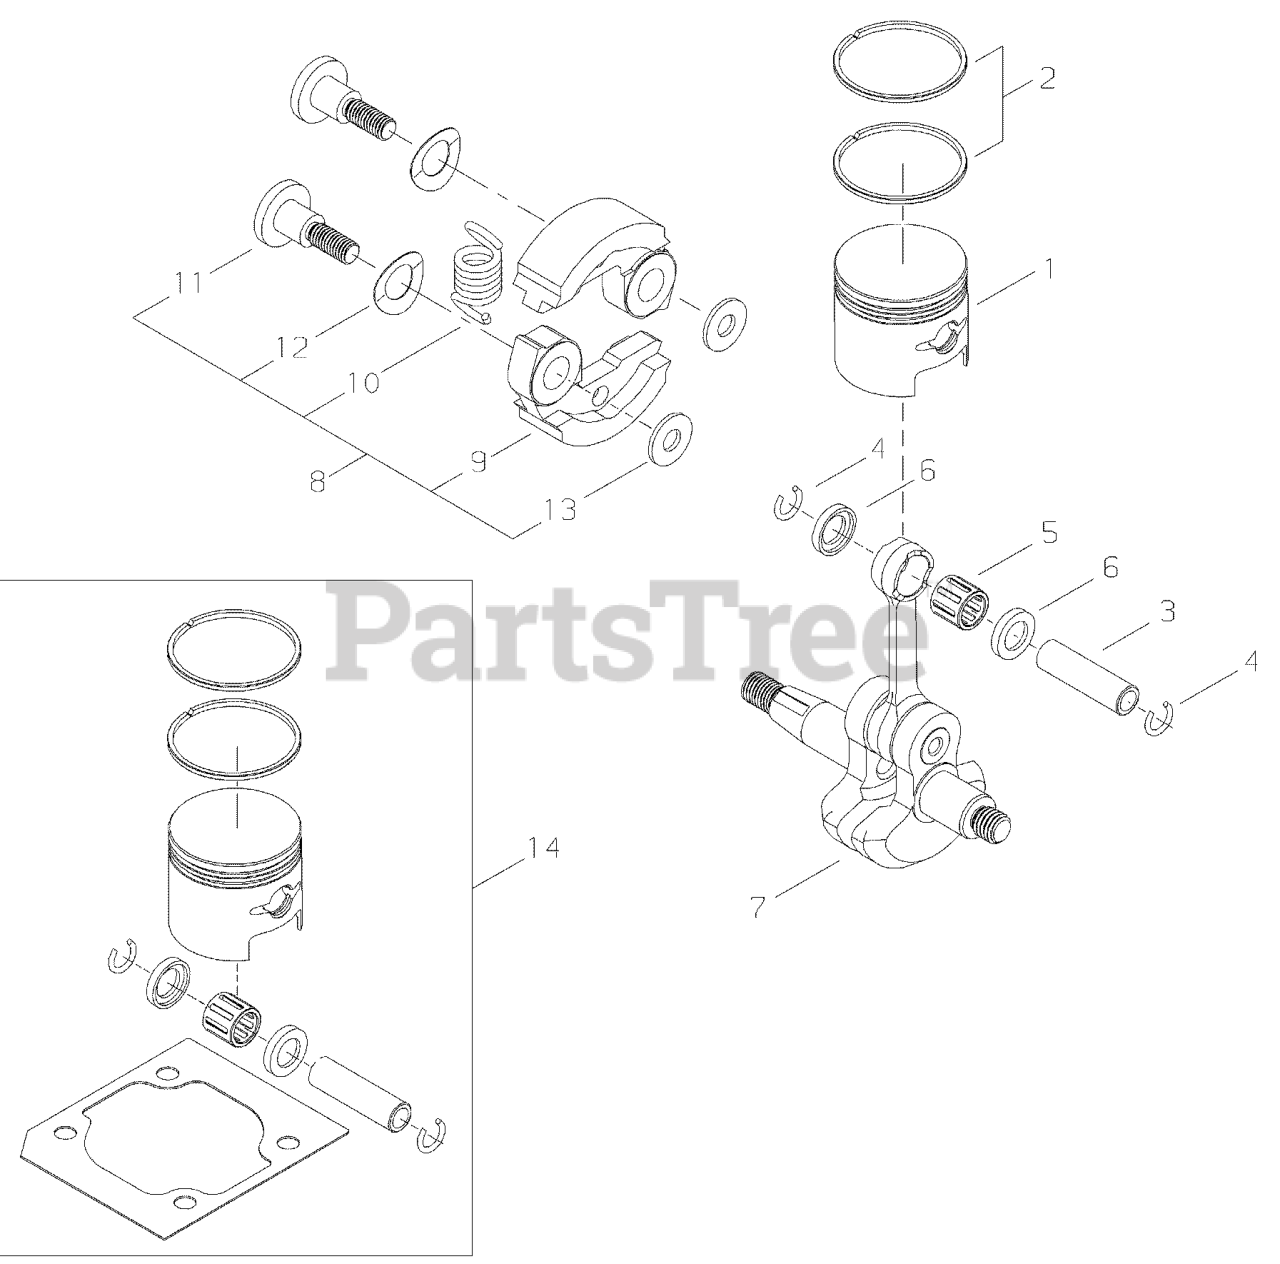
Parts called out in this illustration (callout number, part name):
1	PISTON
2	RING, PISTON
3	PIN, PISTON
4	RING, RETAINING
5	BEARING, NEEDLE - 8
6	SPACER, PISTON
7	CRANKSHAFT ASSY
8	CLUTCH SHOE ASSY
9	SHOE, CLUTCH
10	SPRING, CLUTCH
11	BOLT, CLUTCH
12	WASHER - SPRING
13	WASHER - 6
14	PISTON KIT
